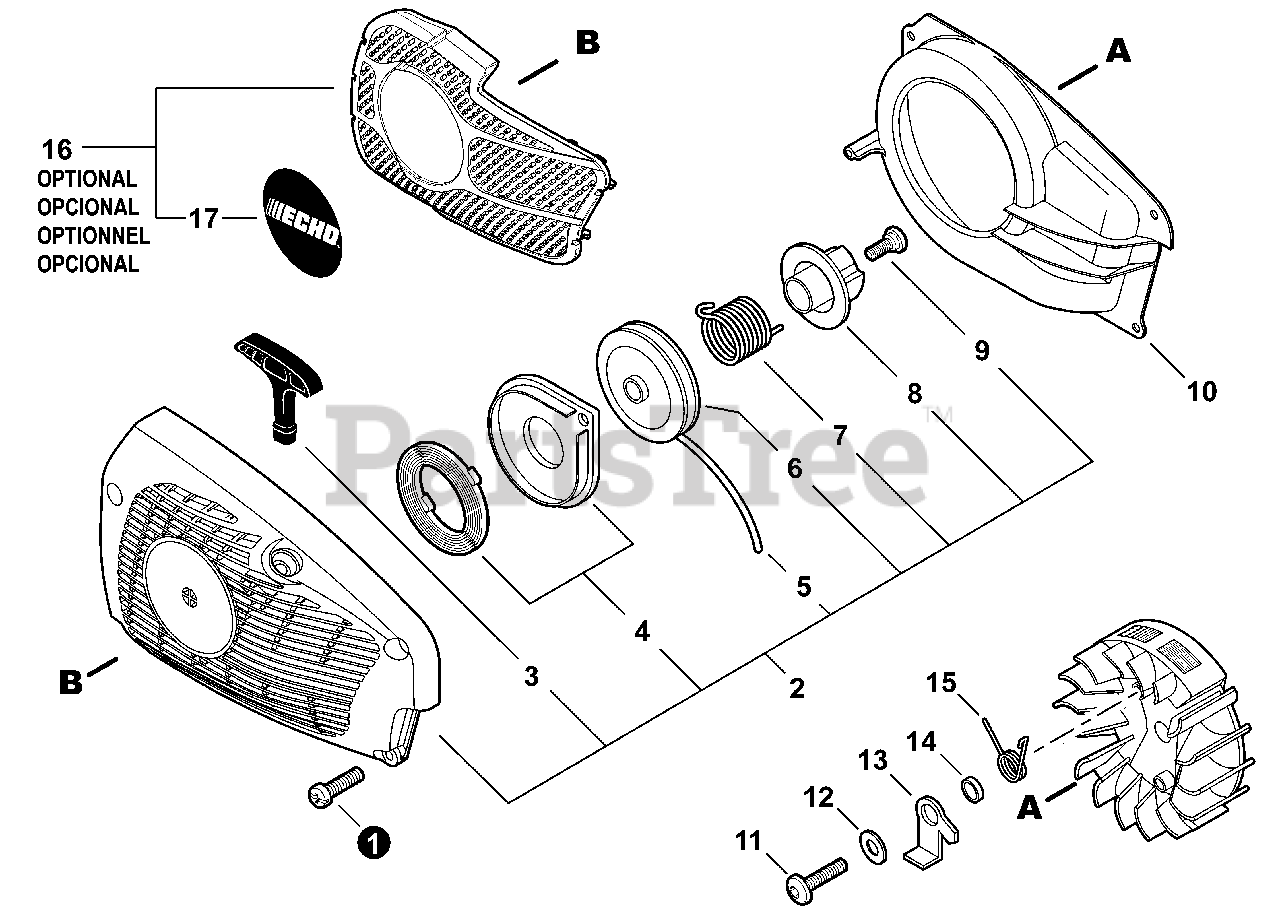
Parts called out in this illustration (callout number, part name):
1	BOLT, TORX 4×16
2	STARTER ASSY, RECOIL
3	GRIP, STARTER
4	SPRING KIT, RECOIL
5	ROPE, STARTER 3.5×900
6	REEL, ROPE
7	SPRING, RETURN
8	PLATE, CAM
9	SCREW
10	COVER, FAN
11	BOLT 5×14
12	WASHER 5.5×12×0.8
13	PAWL, STARTER
14	SPACER 5.2×8×2.1
15	SPRING, TORSION
16	SHIELD, DEBRIS
17	LABEL, ECHO
